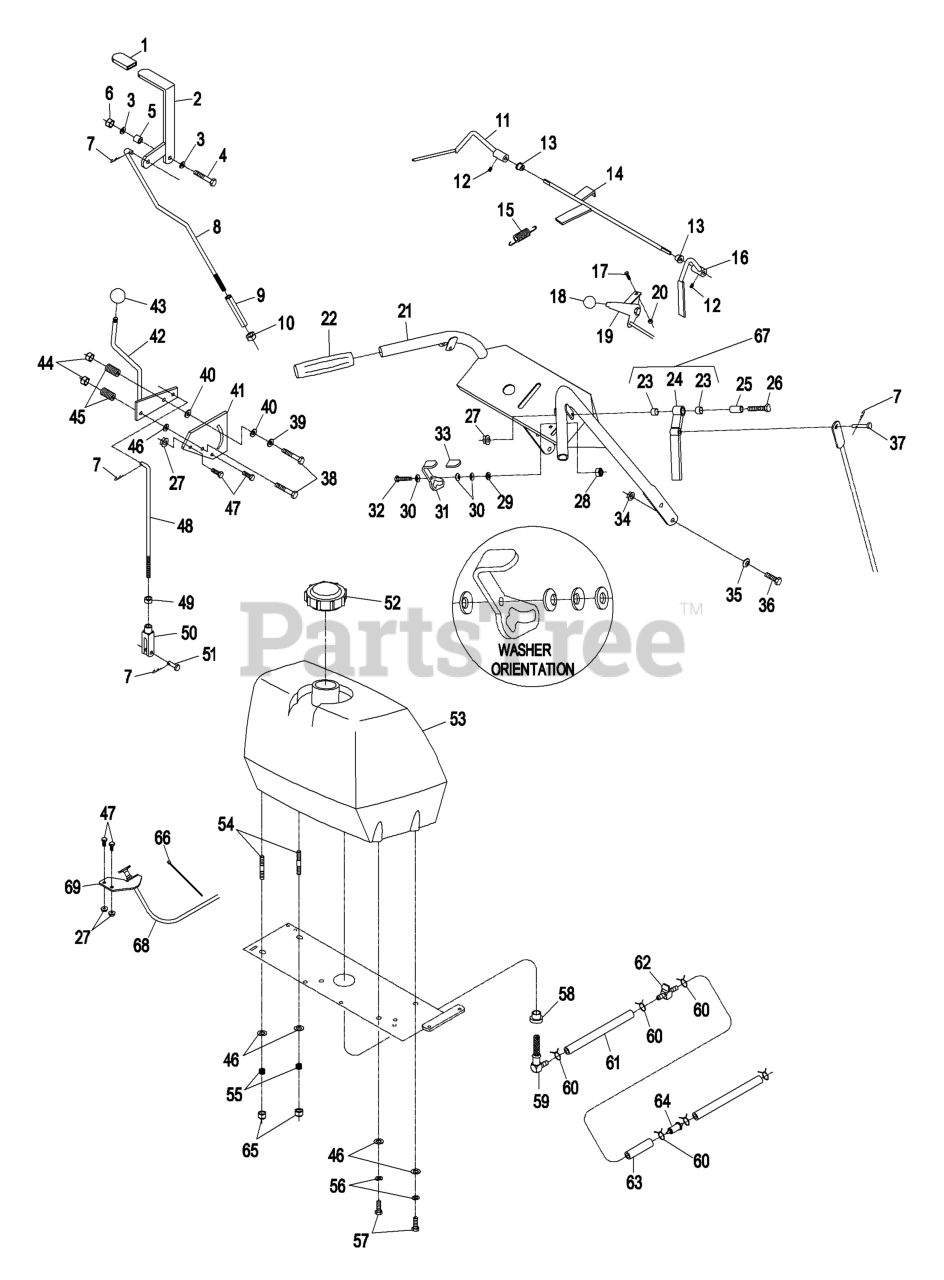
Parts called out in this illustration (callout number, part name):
1	GRIP-LEVER
3	WASHER-FLAT
4	SCREW-HH
5	BUSHING-LEVER, LIFT
6	NUT-LOCK, NI
7	PIN-COTTER
8	LINKAGE,UPPER
9	TURNBUCKLE
10	NUT-HEX
11	LEVER-LH
12	SCREW-SET
13	BUSHING-NYLON
14	WLD,ROD OPC
15	SPRING-EXTENSION
16	LEVER-RH
17	BOLT-CARR
18	KNOB-BALL
19	THROTTLE CABLE ASM
20	NUT-LOCK, NI
23	BUSHING-SLEEVE
25	BUSHING-LEVER, DRIVE
26	SCREW-HH
28	NUT-LOCK, NI
29	WASHER-FLAT
30	WASHER-SPRING
32	SCREW-HH
33	GRIP-LATCH
34	NUT-HHF, WHIZ
35	WASHER-BELLEVILLE
36	SCREW-HH
37	PIN-CLEVIS
38	SCREW-HH
39	WASHER-FRICTION
40	WASHER-FRICTION
41	PLATE-LEVER, SHIFTER
43	KNOB-BALL
44	NUT-LOCK, NI
45	SPRING-COMPRESSION
46	WASHER-PLAIN
47	SCREW-HH
48	ROD,SPEED CONTROL
49	NUT-JAM
50	YOKE-ADJUSTABLE
51	PIN-CLEVIS
52	CAP-FUEL
54	STUD
55	SPRING-TANK, FUEL
56	WASHER-LOCK
57	SCREW-HH
59	ELBOW-TANK, FUEL
61	HOSE-FUEL
62	VALVE-FUEL
63	HOSE-FUEL
64	Filter W/6" Fuel Line
65	NUT-LOCK, NI
66	TIE-CABLE
67	RH DRIVE LEVER ASM
68	CABLE-CHOKE
69	BRACKET-CABLE, CHOKE
